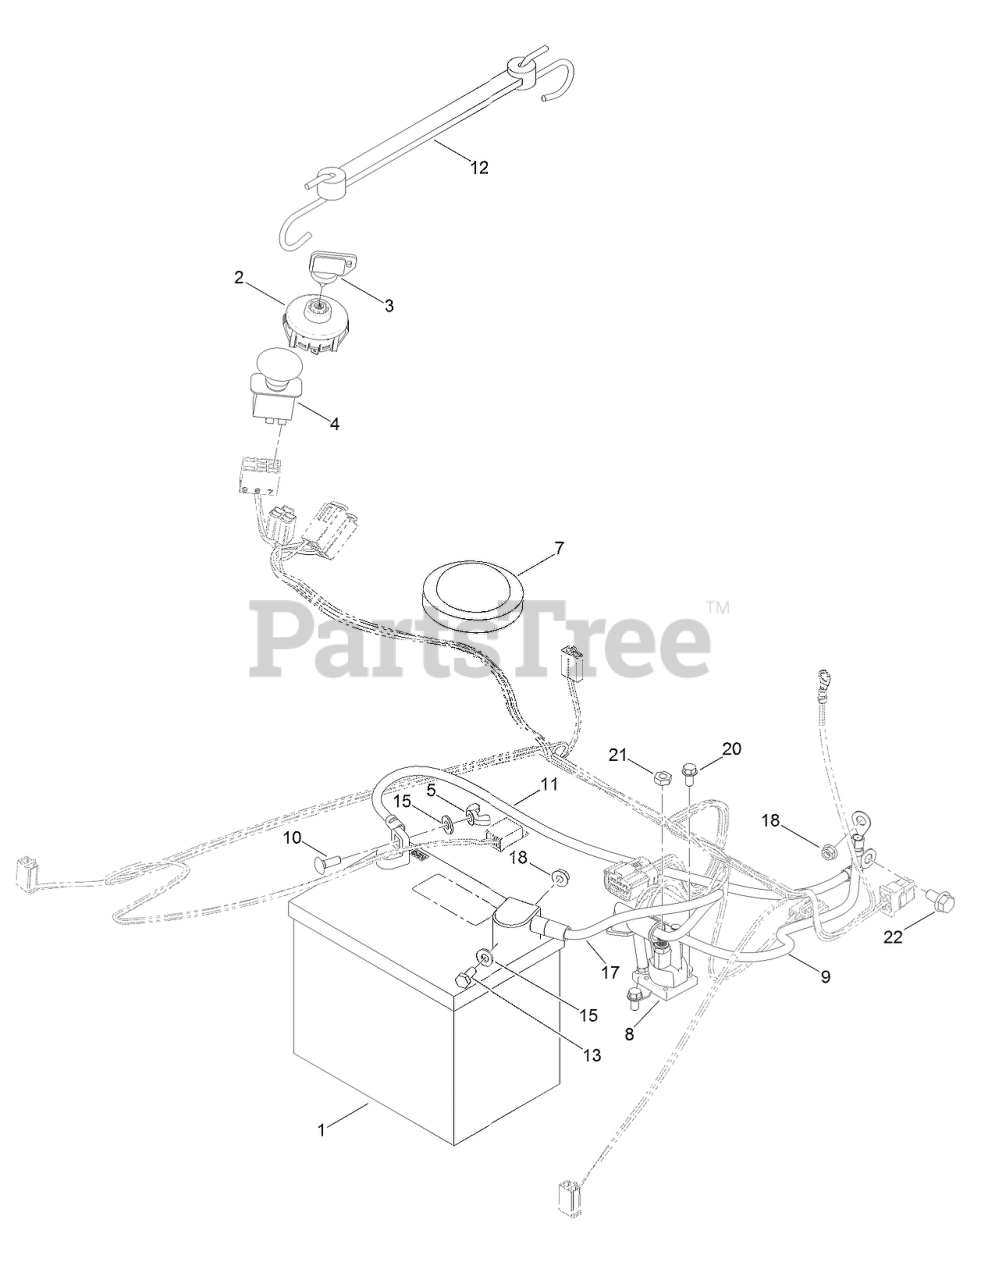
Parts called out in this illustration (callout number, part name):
1	BATTERY
2	SWITCH-IGNITION
3	KEY-IGNITION
4	SWITCH-PTO
5	NUT-WING
7	SWITCH-SEAT
8	SOLENOID
9	CABLE-BATTERY, RED
10	BOLT-CARR
11	CABLE-BATTERY, BLACK
12	HOLDDOWN-BATTERY
13	SCREW-HH
15	WASHER-FLAT
17	CABLE-BATTERY, RED
18	NUT-HF
20	SCREW-HWH
21	NUT-JAM
22	SCREW-HHF
